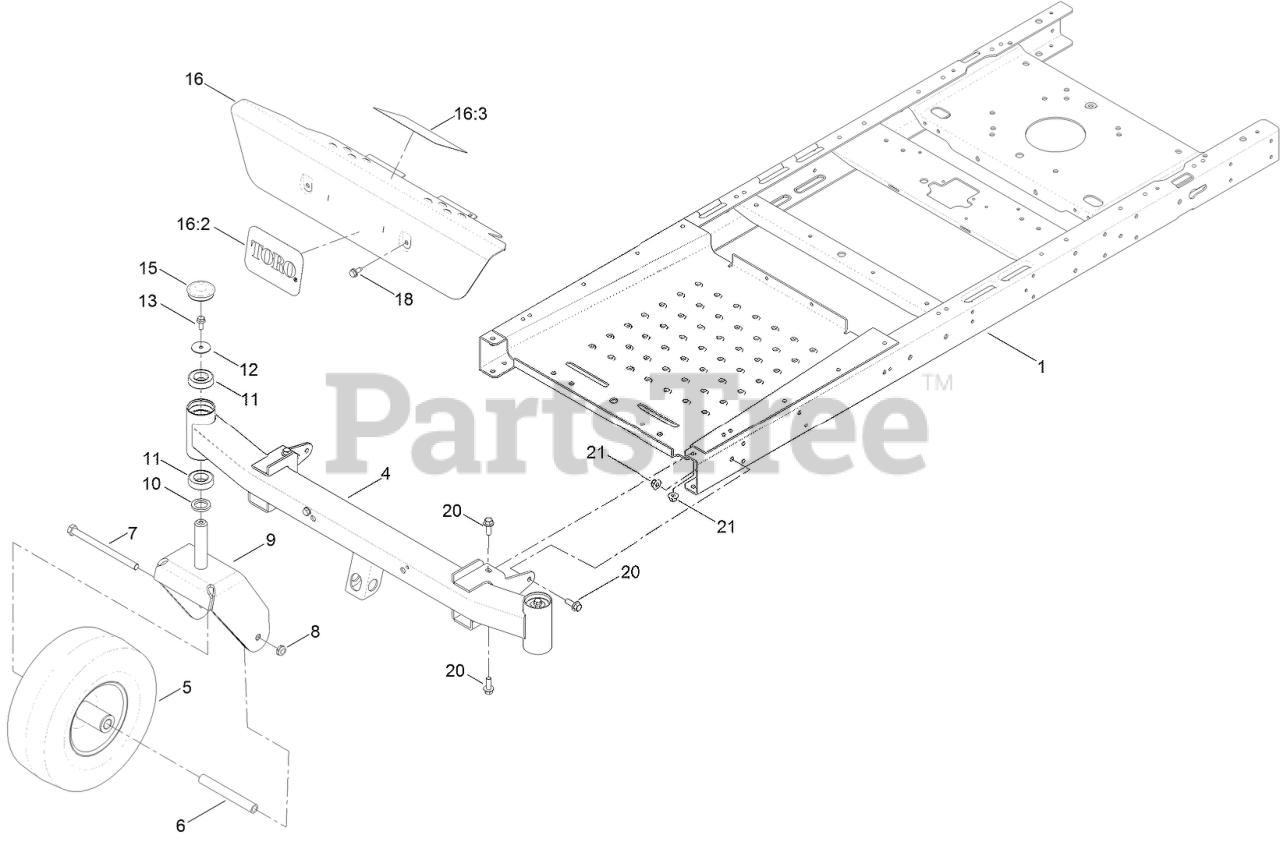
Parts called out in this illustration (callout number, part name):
1	FRAME ASM
4	AXLE ASM
5	13 INCH WHEEL AND TIRE ASM
6	SPANNER
7	SCREW-HH
8	NUT-LOCK, NI
9	FORK-CASTER
10	WASHER-THRUST
11	BEARING-BALL
12	WASHER-FLAT
13	SCREW-HHF
15	CAP-GREASE
16	Footrest ASM
16:2	DECAL
16:3	DECAL-DANGER
18	SCREW-HWHTF
20	SCREW-HHF
21	NUT-HF, NI
